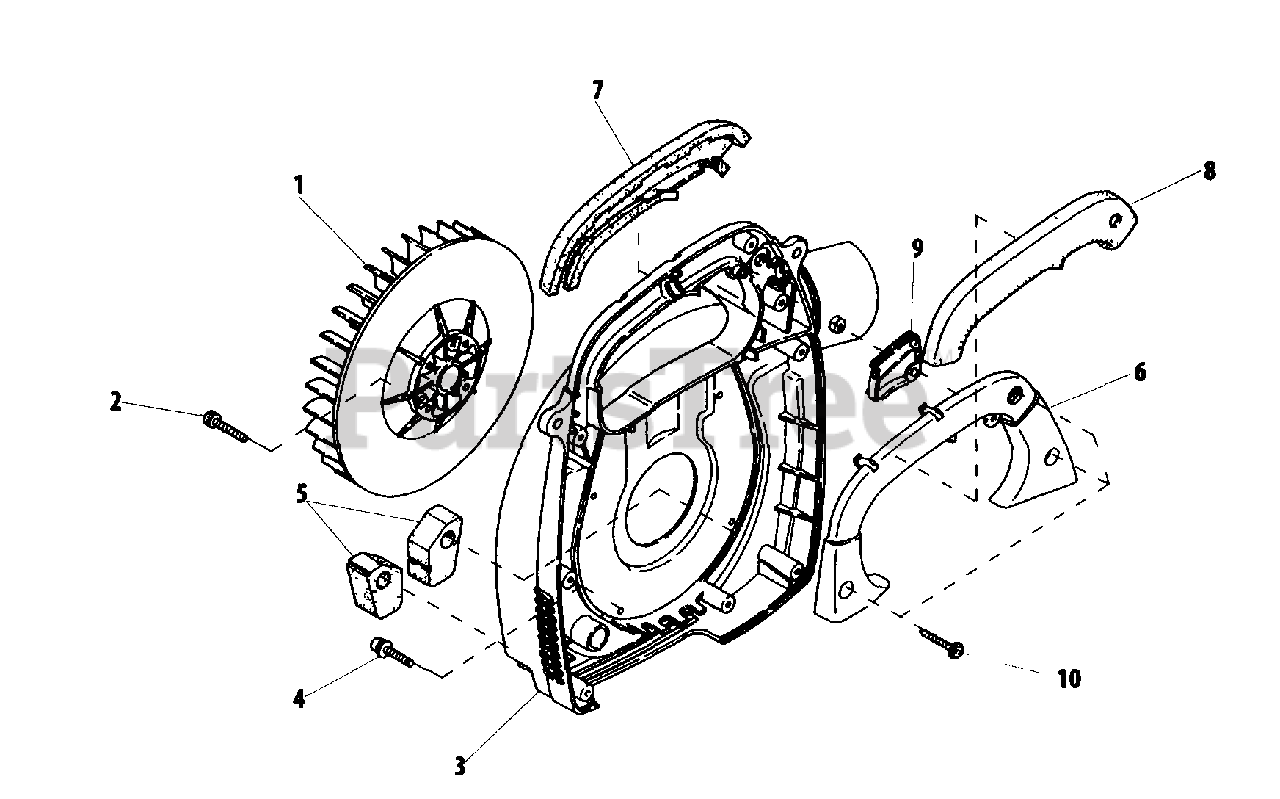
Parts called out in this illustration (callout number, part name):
1	IMPELLER
2	BOLT 5×20
3	COVER, FAN - RIGHT
4	SCREW
5	CUSHION
6	COVER, HANDLE
7	GRIP, LEFT
8	GRIP, RIGHT
9	TRIGGER, THROTTLE
10	SCREW M5
